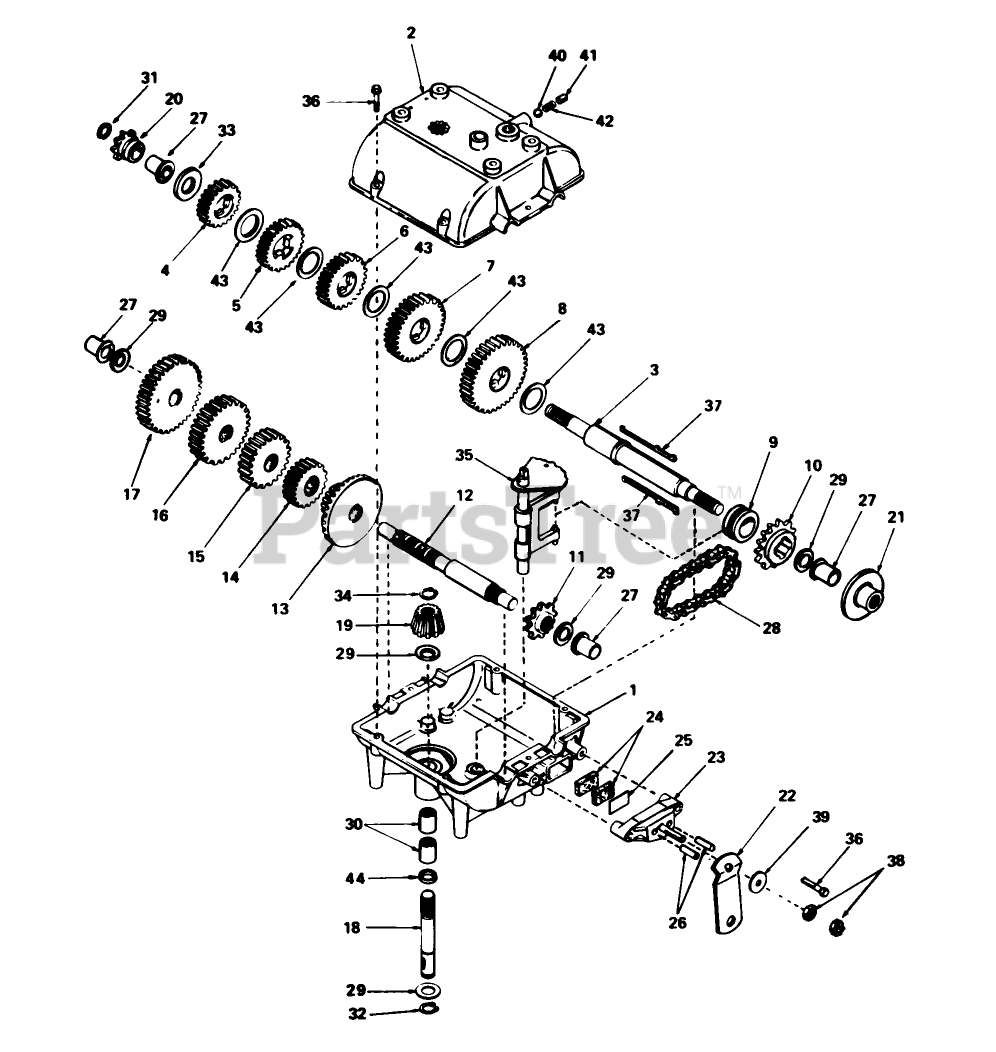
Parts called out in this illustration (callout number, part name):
1	Case-Transmission
2	Cover-Transmission
3	Shaft-Output Brake
4	A Gear-Spur (20 teeth)
5	Gear-Spur (22 teeth)
6	Gear-Spur, 25 Teeth
7	Gear-Spur, 30 Teeth
8	Gear-Spur, 35 Teeth
9	Collar-Shift
10	Sprocket-18 Teeth
11	Sprocket-9 Teeth
12	Countershaft
13	Gear-Bevel (42 tooth 15 tooth spur gear)
14	Gear-Spur, 20 Teeth
15	Gear-Spur, 25 Teeth
16	Gear-Spur (28 teeth)
17	Gear-Spur (30 teeth)
18	Shaft-Input
19	Bevel Pinion-Input
20	Sprocket (8Teeth)
21	Disk
22	Lever Brake
23	Holder-Brake Pad
24	Brake Pad
25	Brake Pad Plate
26	Dowel Pin
27	Bushing, Flanged
28	Chain-Roller #41
29	Washer
30	Bearing-Needle
31	Piston Asm (.020 O S)
32	Ring-Snap
33	Washer
34	Ring-Retainer
35	Rod and Fork ASM
36	Ring Set (.020 O S)
37	Key
38	Locknut
39	Washer
40	Ball-Steel
41	Screw-Set
42	Spring
43	Washer
44	O Ring
